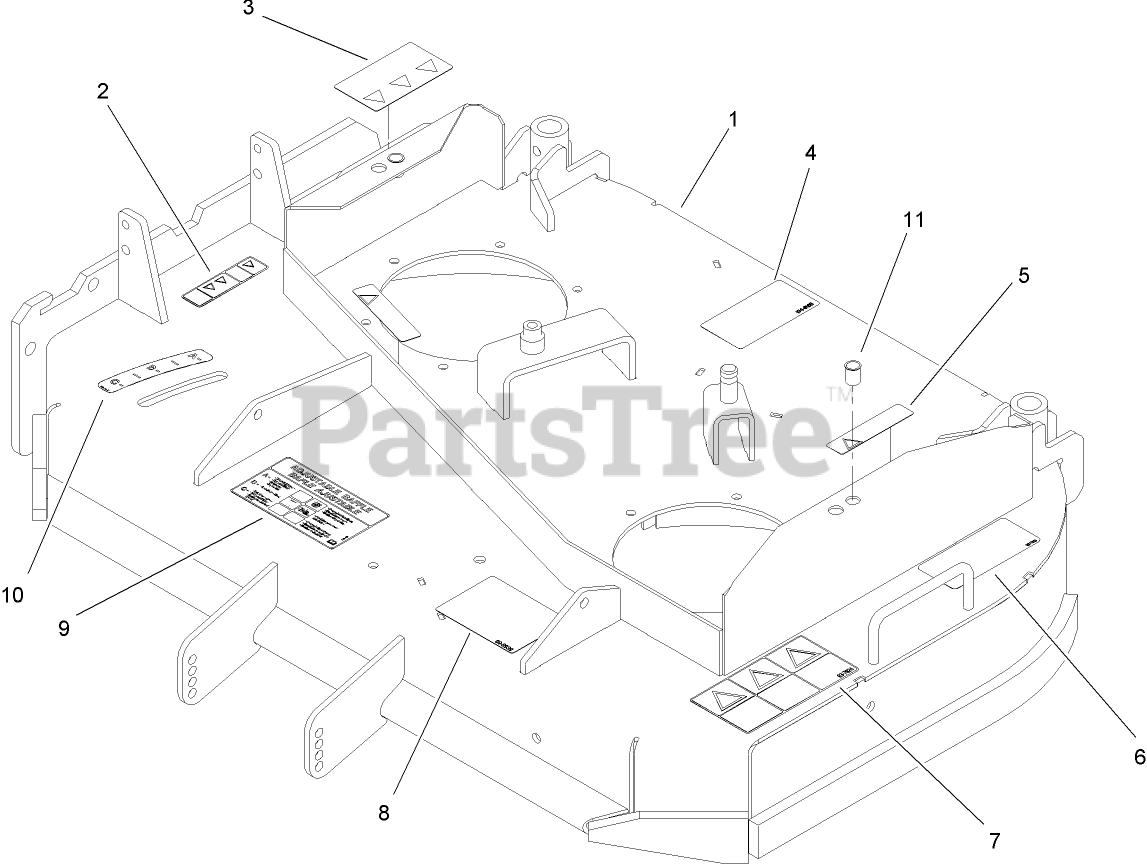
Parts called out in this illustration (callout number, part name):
1	Deck ASM
2	DECAL-WARNING, DEFLECTOR
3	DECAL-DANGER
5	DECAL-WARNING
6	DECAL-TORQUE, BLADE BOLT
7	DECAL-DANGER
8	DECAL-ANTI SCALP
9	DECAL-ADJUSTMENT, BAFFLE
10	DECAL-SETTING, BAFFLE
11	INSERT-NUT
